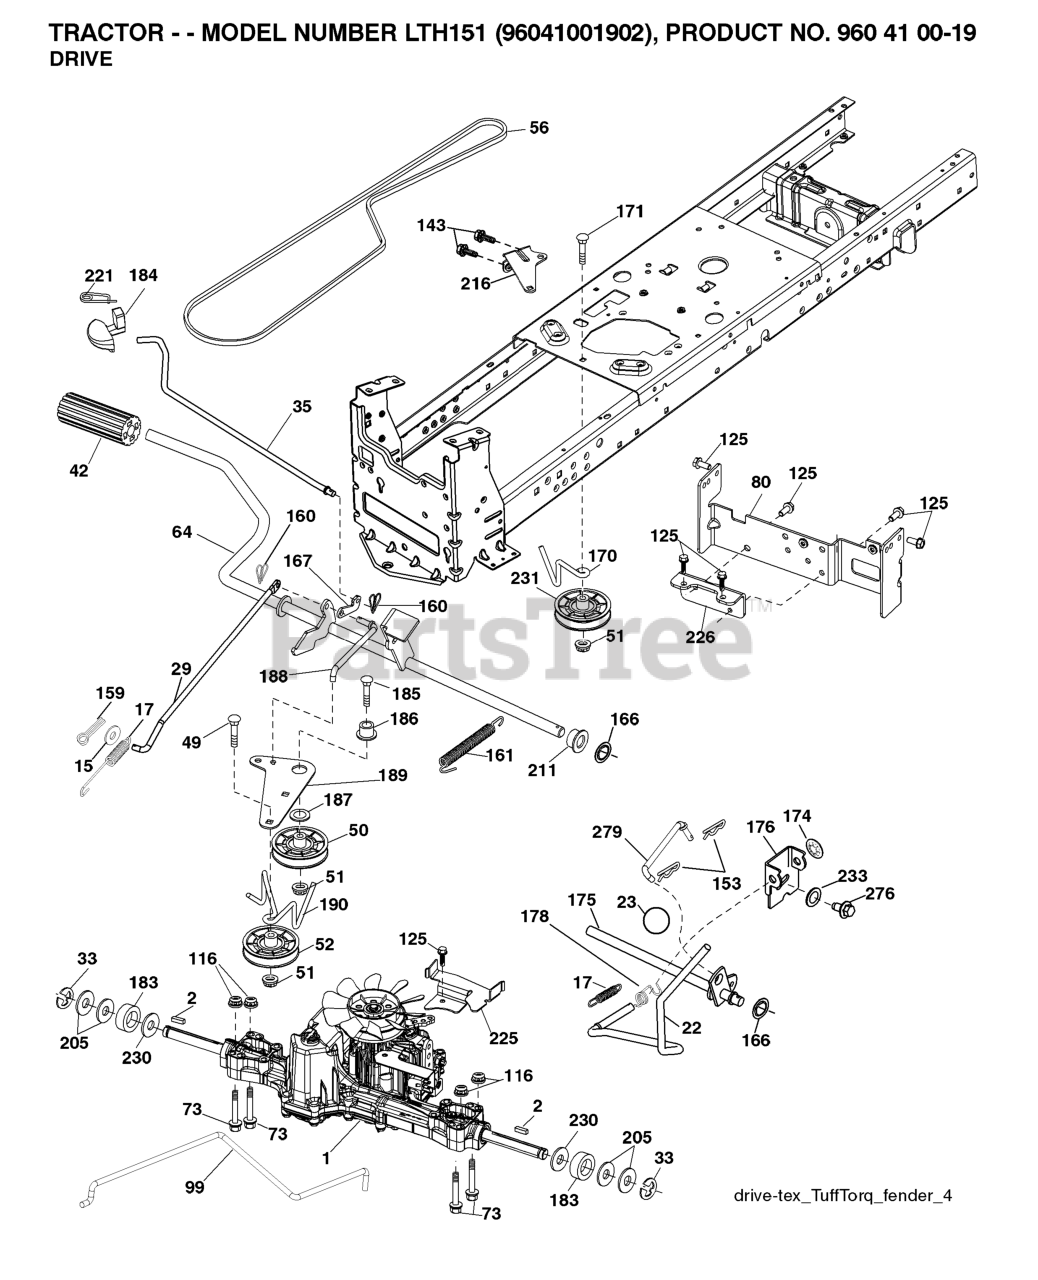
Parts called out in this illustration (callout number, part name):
2	SQUARE KEY
15	WASHER
17	SPRING.BRAKE.K46.GREEN
22	ROD.SHIFT.FENDER.TLT.2006
23	KNOB.DUCKHEAD.1/2
29	ROD.BRAKE.K46
35	ROD.BRAKE.PARKING.GT.H
42	PEDAL COVER T
50	IDLER.FLAT.910.OFFSET
51	NUT LOCK FLG 3/8-16 UNC
52	IDLER.V-GROOVE.910.OFFSET
56	V-BELT.MOWER.92.40.42/K46
64	SHAFT.ASM.PEDAL.BRAKE.
73	BOLT HEX 5/16-18 GR 5
80	STRAP TORQUE.ASM.K46/18"TEX
99	ROD ASM BYPASS
116	NUT LOCK HEX FLANGE 5/16-18
125	SCREW
143	Screw 5/16-18 x 1/2 Hex, Self Tapping 5/16-18 x 1/2
153	RETAINER M
159	COTTER PIN
160	RETAINER CLIP
161	SPRING, RETURN LT
166	NUT.PUSH.625.2006
167	LATCH.BRAKE.SPRING
170	KEEPER.V-IDLER.CENTER.
174	NUT.PUSH.500.2006
175	SHAFT.ASM.SHFT.T2.TLT
176	ARM.CLEVIS.ROD.SHIFT
178	SPRING.SHIFT.GT2006
183	SPACER AXLE
184	HANDLE PARKING BRAKE
186	SPACER.RETAINER
187	WASHER 12/32X2X10GA
188	RP.LINK.CLUTCH.GROUND.DRIVE
189	BELLCRANK.GROUND.DRIVE.TEX.
190	KEEPER.BELLCRANK.DRIVE
211	BUSHING.SHAFT.BRAKE.HAND
216	BRACKET.PULLEY.IDLER.W/TEX
221	RETAINER.SPRING.CLIP.H
225	KEEPER.BELT.TRANSAXLE.K46
226	BRACKET.MOUNT.TORQUE.K46.TLT
230	WASHER.HARDENED
231	IDLER.V-GROOVE.1.688.OFFSET
233	WASHER SERRATED
276	BOLT FIN HEX 7/16-14 X 1
279	LINK.SHIFT.
